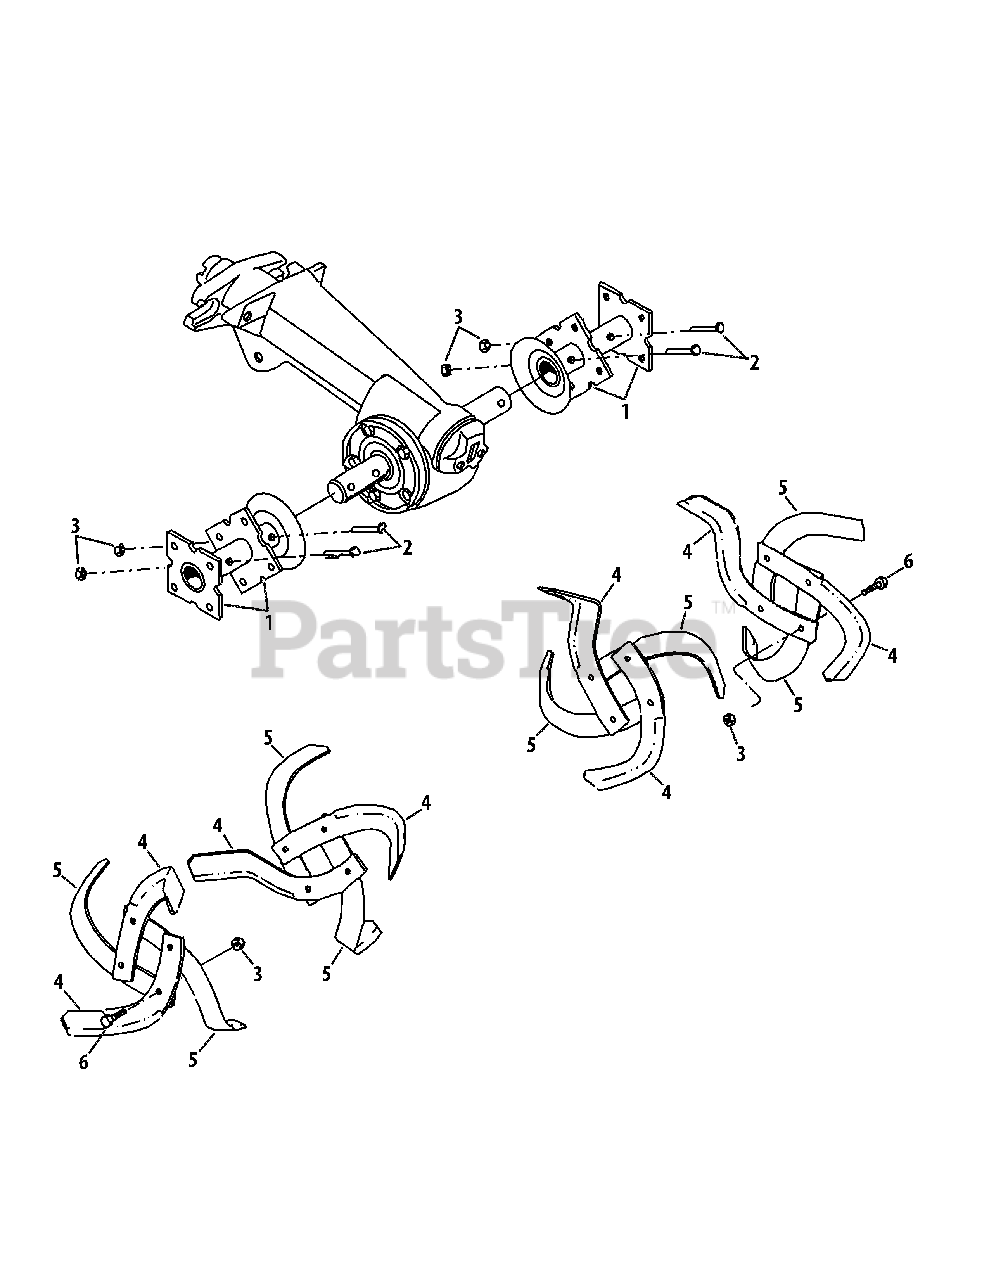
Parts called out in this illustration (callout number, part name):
2	Hex Bolt, 3/8"-16 x 2"
3	Hex Locknut, 3/8"-16
4	Bolo Tine Left
5	Bolo Tine Right
6	Hex Head Screw, 3/8"-16 x 1"
